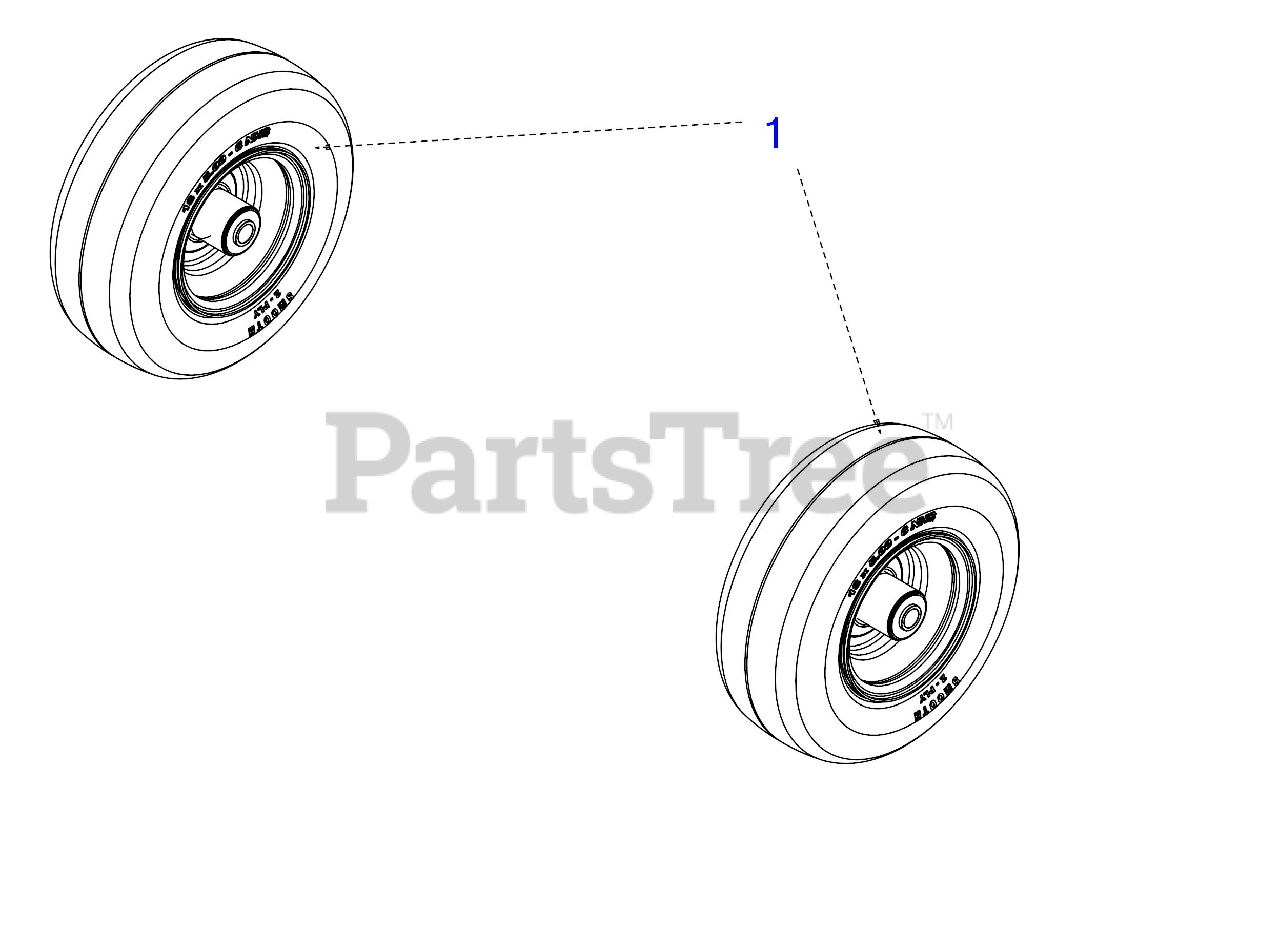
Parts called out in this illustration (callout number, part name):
1	CASTER TIRE-SMOOTH 2 PLY 13X5.0-6
1	BRG-BALL .754 ID x 1.750 OD
1	TUBELESS VALVE
1	GREASE FITTING
